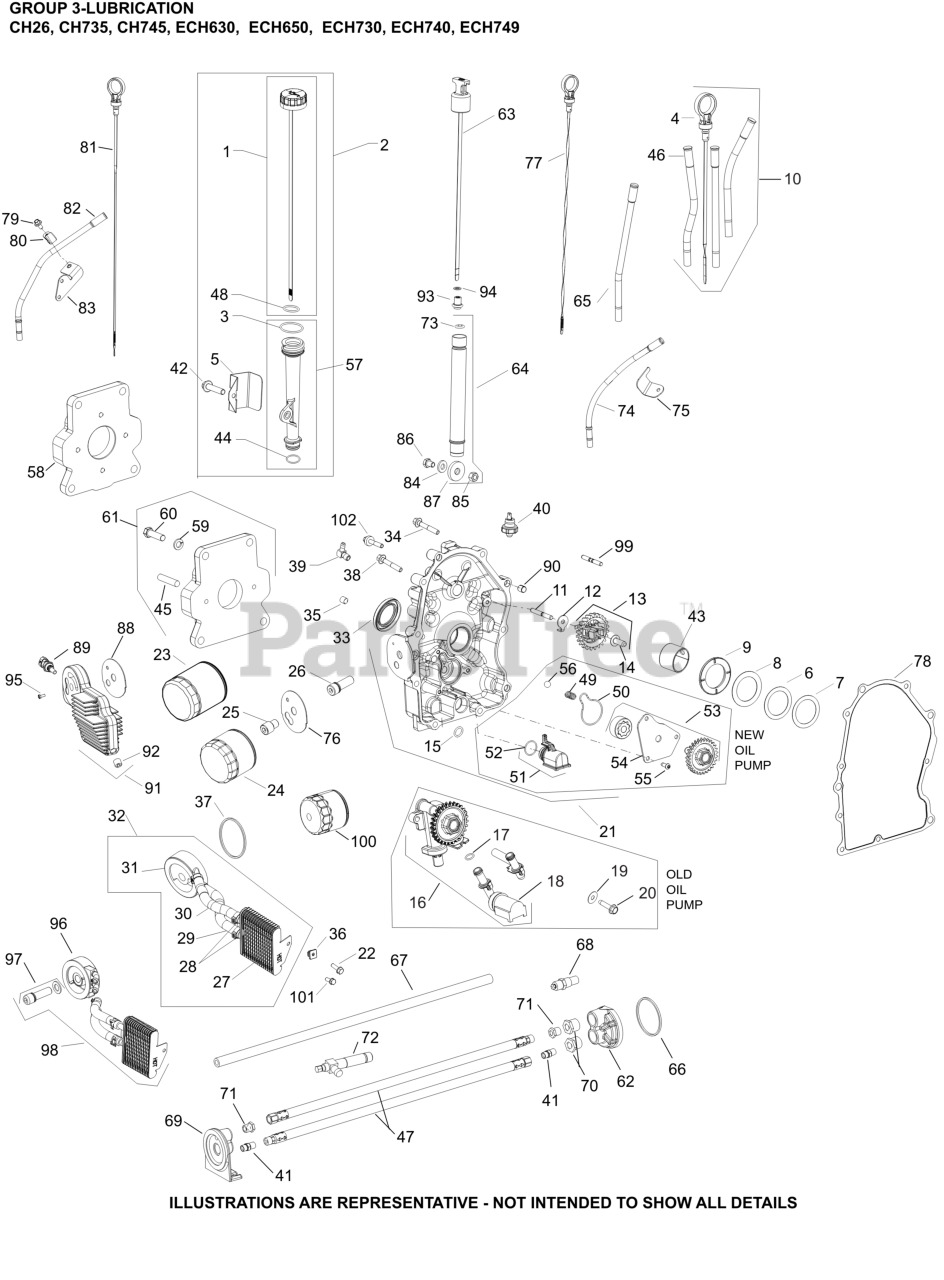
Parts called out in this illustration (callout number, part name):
10	KIT, DIPSTICK/DIPSTICK TUBES
12	TAB, LOCKING
13	KIT, GOVERNOR GEAR W/PIN
14	PIN, GOVERNOR REGULATING
21	KIT, CLOSURE PLATE ASSY
24	OIL FILTER
28	CLAMP, HOSE LOW PROFILE
30	KIT, HOSE 140MM
35	PLUG, CTSK PIPE 1/8"
36	NUT, PLASTIC - BLACK
37	O-RING, OIL COOLER
38	SCREW, FLG M8X1.25X45
38	SCREW, HEX FLANGE
40	SENSOR, OIL PSI
49	SPRING, COMPRESSION
50	SEAL, OIL PUMP COVER
51	PICK-UP ASSEMBLY, OIL
52	O-RING, OIL PICK-UP
53	PUMP ASSEMBLY, OIL
54	COVER, OIL PUMP
55	SCREW, BUTTON HEAD
56	PRESSURE RELIEF BALL
97	KIT, OIL FILTER NIPPLE
98	KIT, OIL COOLER
99	SHAFT, GOVERNOR GEAR
101	SCREW, HEX HEAD
102	WASHER, FLAT
